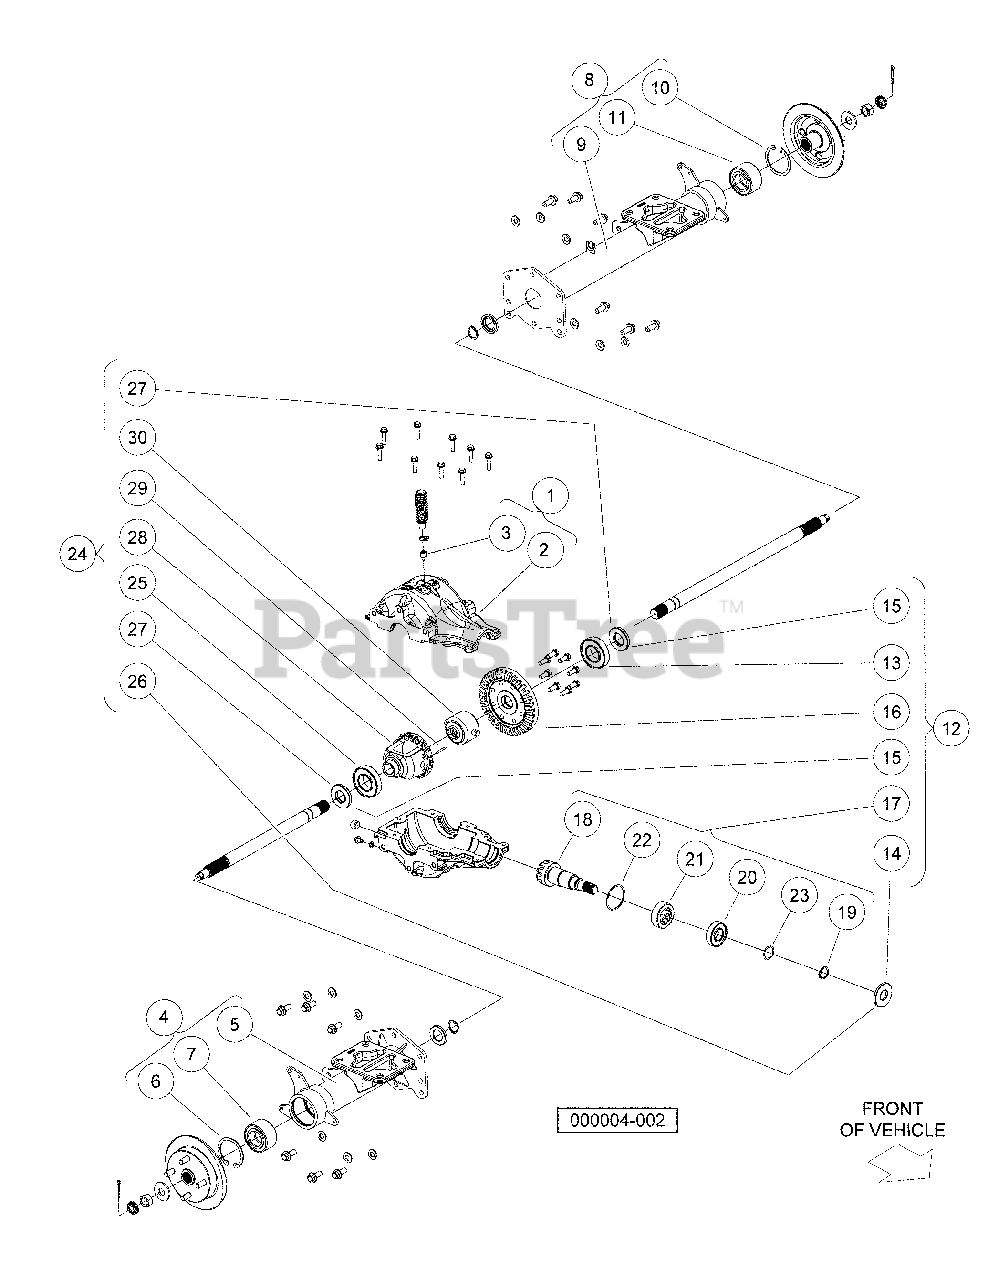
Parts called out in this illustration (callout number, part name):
1	Asm, Gearcase, Upper
2	Gearcase, Upper, Machined
3	Vent, Top, Upper Housing
4	Asm, Axle Tube, RH
5	Weldment, Axle Tube Rh
6	Ring, Retaining, Internal
8	Asm, Axle Tube, LH
9	Weldment, Axle Tube Lh
10	Ring, Retaining, Internal
12	Kit, Rear Axle Gear Repair
13	Bearing, Ball
14	Seal, Dual-Lip 25x 62x 7tc
15	Seal, Dual-Lip 30x 62x 8tc
17	Asm, Pinion W/ Bearings
18	Pinion, I0t Machined
19	Ring, Retaining, External
20	Bearing, Ball
21	Bearing, Needle, Drawn Shell
22	Washer, 2.625 X 2.367 X .06
23	Shim, 1.50 X 1.189 X .008
24	Asm, Differential & Carrier
25	Bearing, Ball
26	Seal, Dual-Lip 25x 62x 7tc
27	Seal, Dual-Lip 30x 62x 8tc
28	Housing, Differential, Mach
29	Pin, Dowel, 4 X 35
30	Asm, Locker, Nongrease/Spacers
